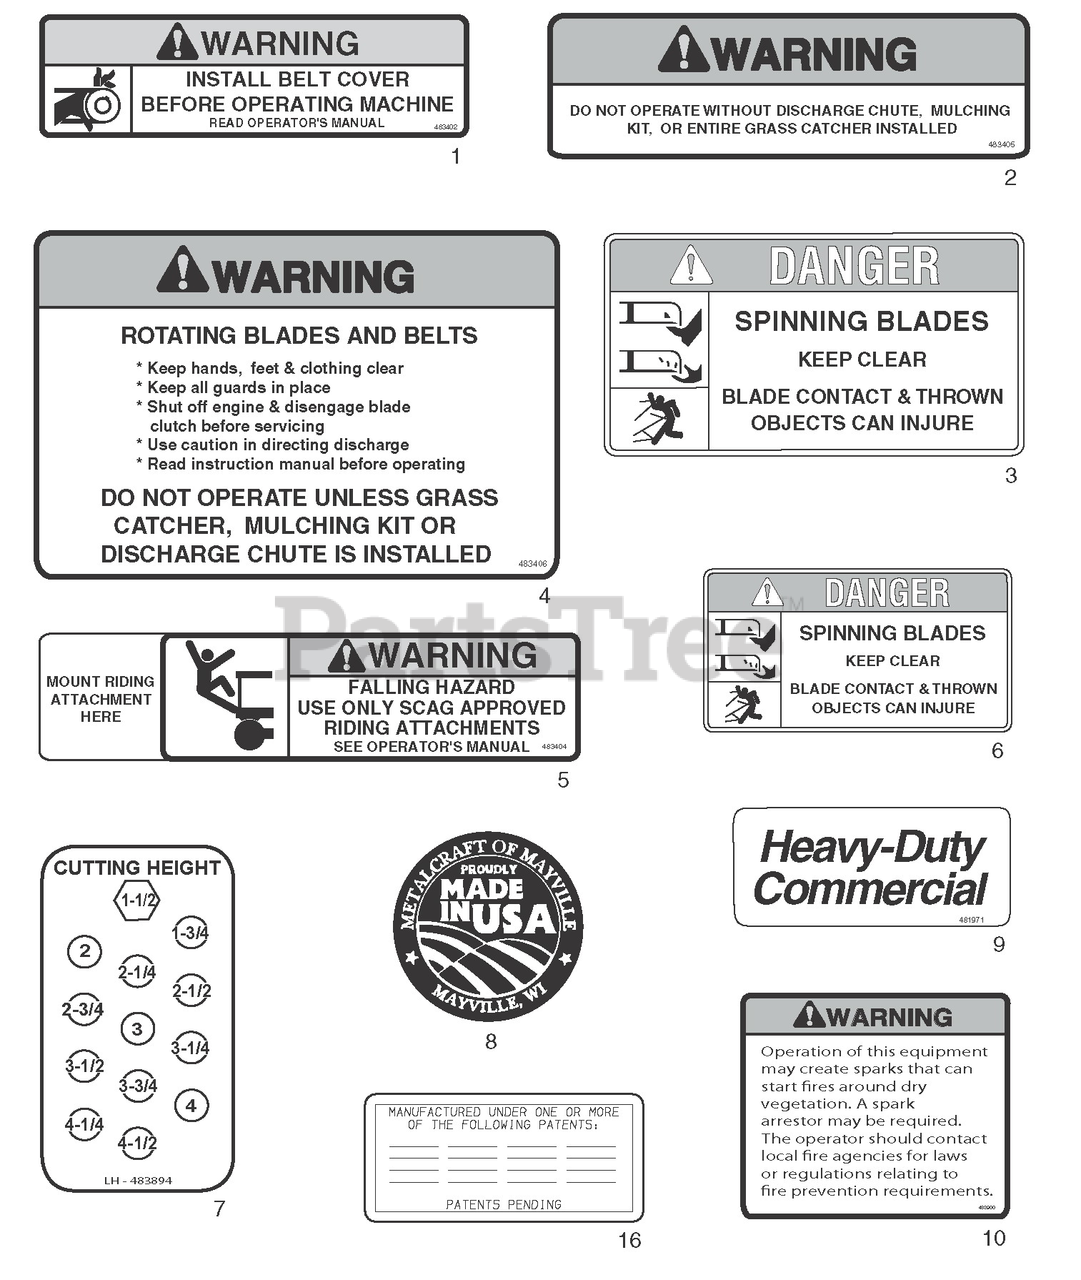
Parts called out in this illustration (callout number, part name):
1	Decal, Belt Cover
2	Decal, Discharge Chute
3	Decal, Spinning Blades
4	Decal, Warning-Rotating Blades
5	Decal, Sulky Attachment
6	Decal, Danger-Spinning Blades
7	Decal, Cutting Height LH
8	Decal, Metalcraft - Made in USA
9	Decal, Heavy Duty Commercial
10	Decal, Warning Spark Arrestor
16	Decal, Patents
